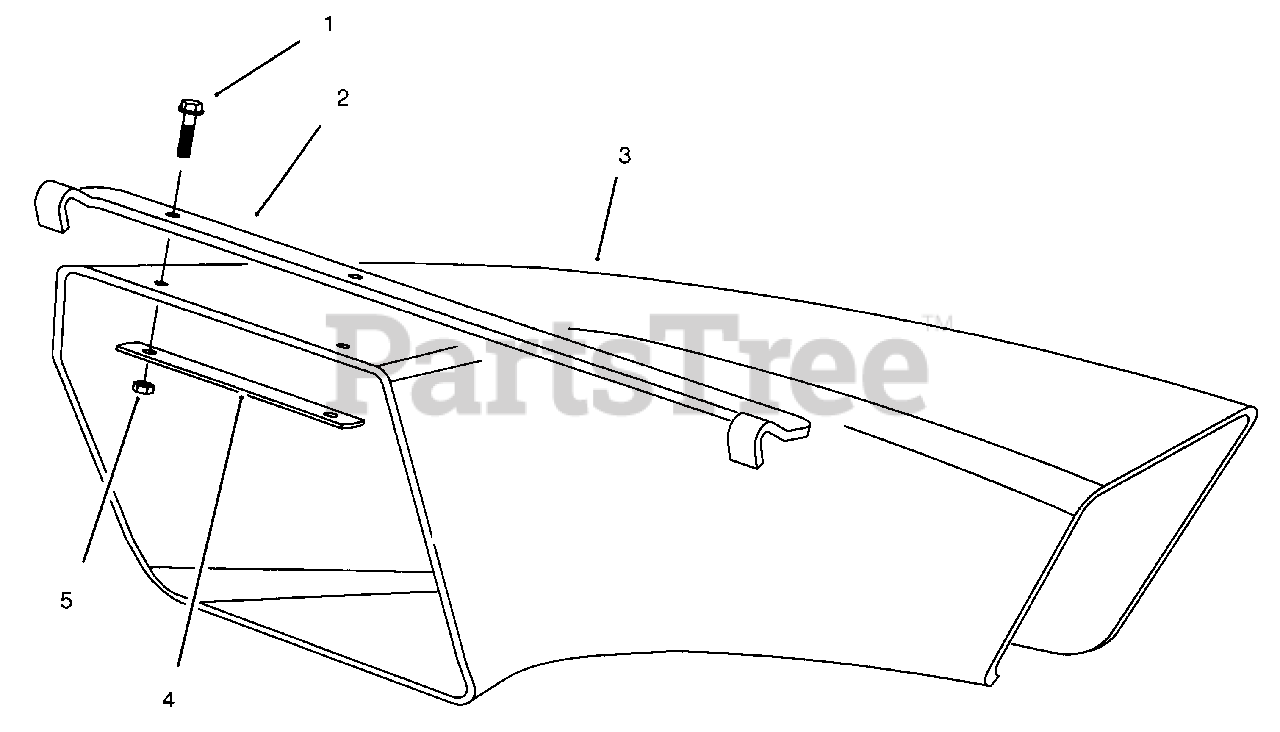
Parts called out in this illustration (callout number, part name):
1	Screw-Hex Washer Hd.
2	Bracket-Chute Hanger
3	Chute-Discharge
4	Nut-Lock
5	Plate-Stress
